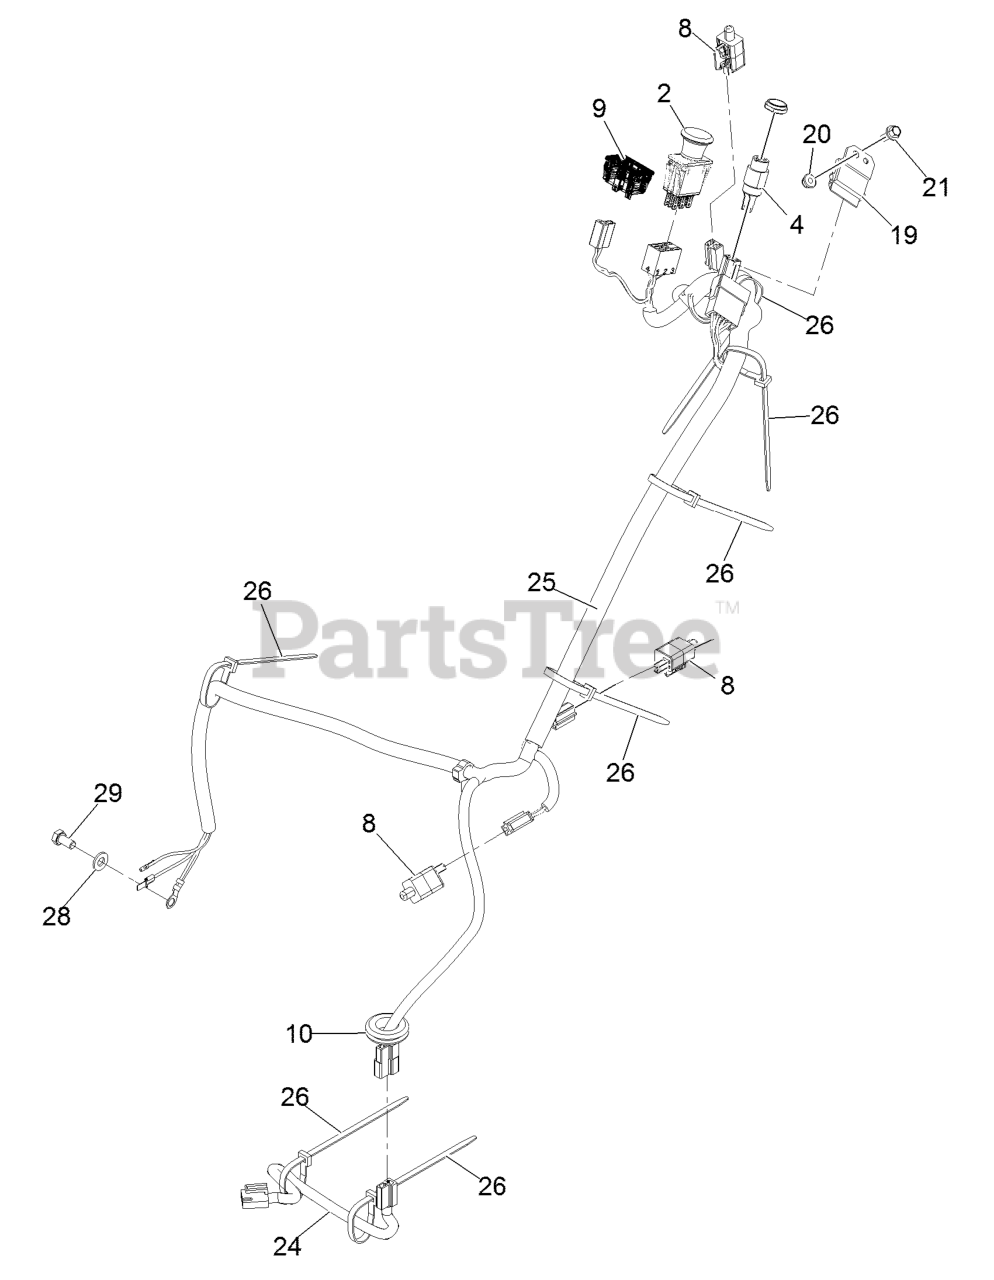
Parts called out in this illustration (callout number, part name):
2	Switch-PTO
4	Switch & Key (Includes Nut & Washer)
4	Nut-Ignition
9	Hour Meter
10	Grommet
19	Module-Interlock
20	Nut-Nyloc 1/4-20 Flg
21	Screw-Head, Flange
24	Harness-Clutch Pigtail
25	Harness-Main
26	Tie-Cable 7 15/16 (Large)
29	Screw-HH M8-1.25 X 16Mm
